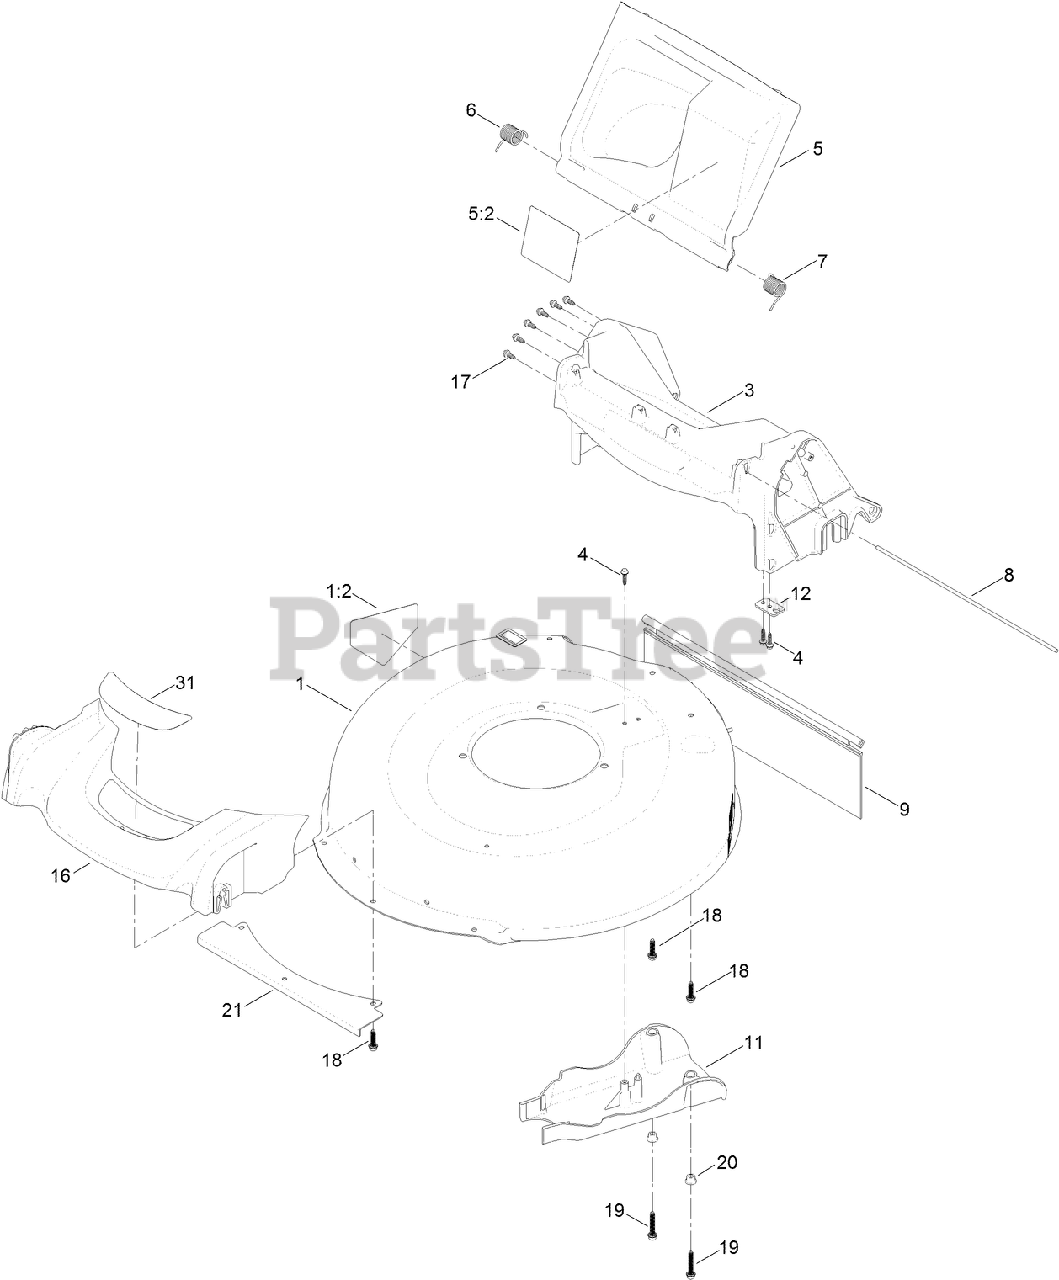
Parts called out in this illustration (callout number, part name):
1	HOUSING ASM
1:2	DECAL-DANGER
4	SCREW-HWH
5	REAR DEFLECTOR ASM
5:2	DECAL-WARNING
6	SPRING-TORSION
7	SPRING-TORSION
8	ROD-DOOR
9	SHIELD-TRAILING
11	COVER-BELT
12	BRACKET-CABLE
16	BUMPER
18	SCREW-FLANGE, PLASTIC
19	SCREW-FLANGE, SERRATED
20	SPACER-FLANGE
21	SHIELD-FRONT
31	DECAL-DECK
